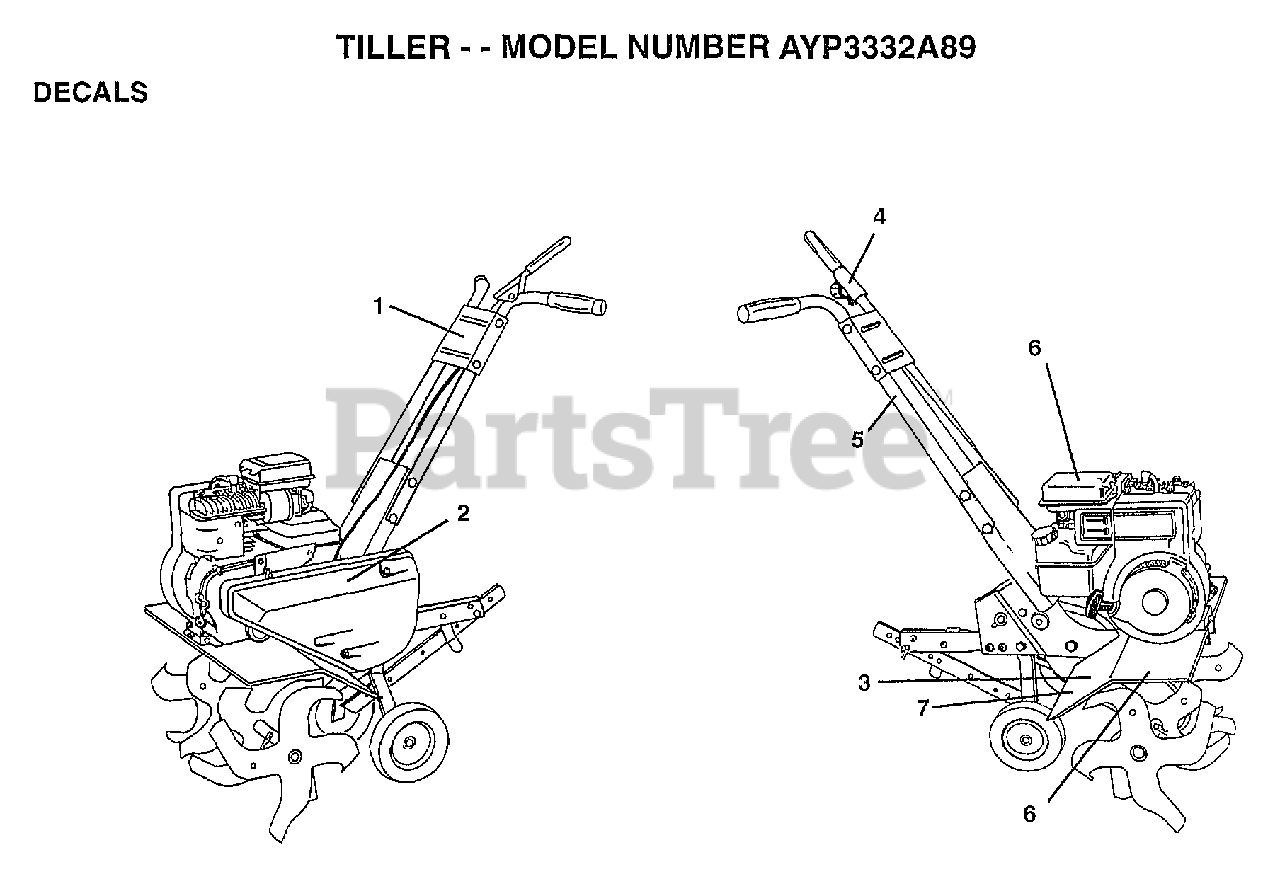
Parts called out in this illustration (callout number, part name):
1	DECAL PANEL CONT
2	DECAL.LOGO
4	DECAL TI
5	DECAL TI
6	DECAL.TINE.SHIELD
7	DECAL TI
